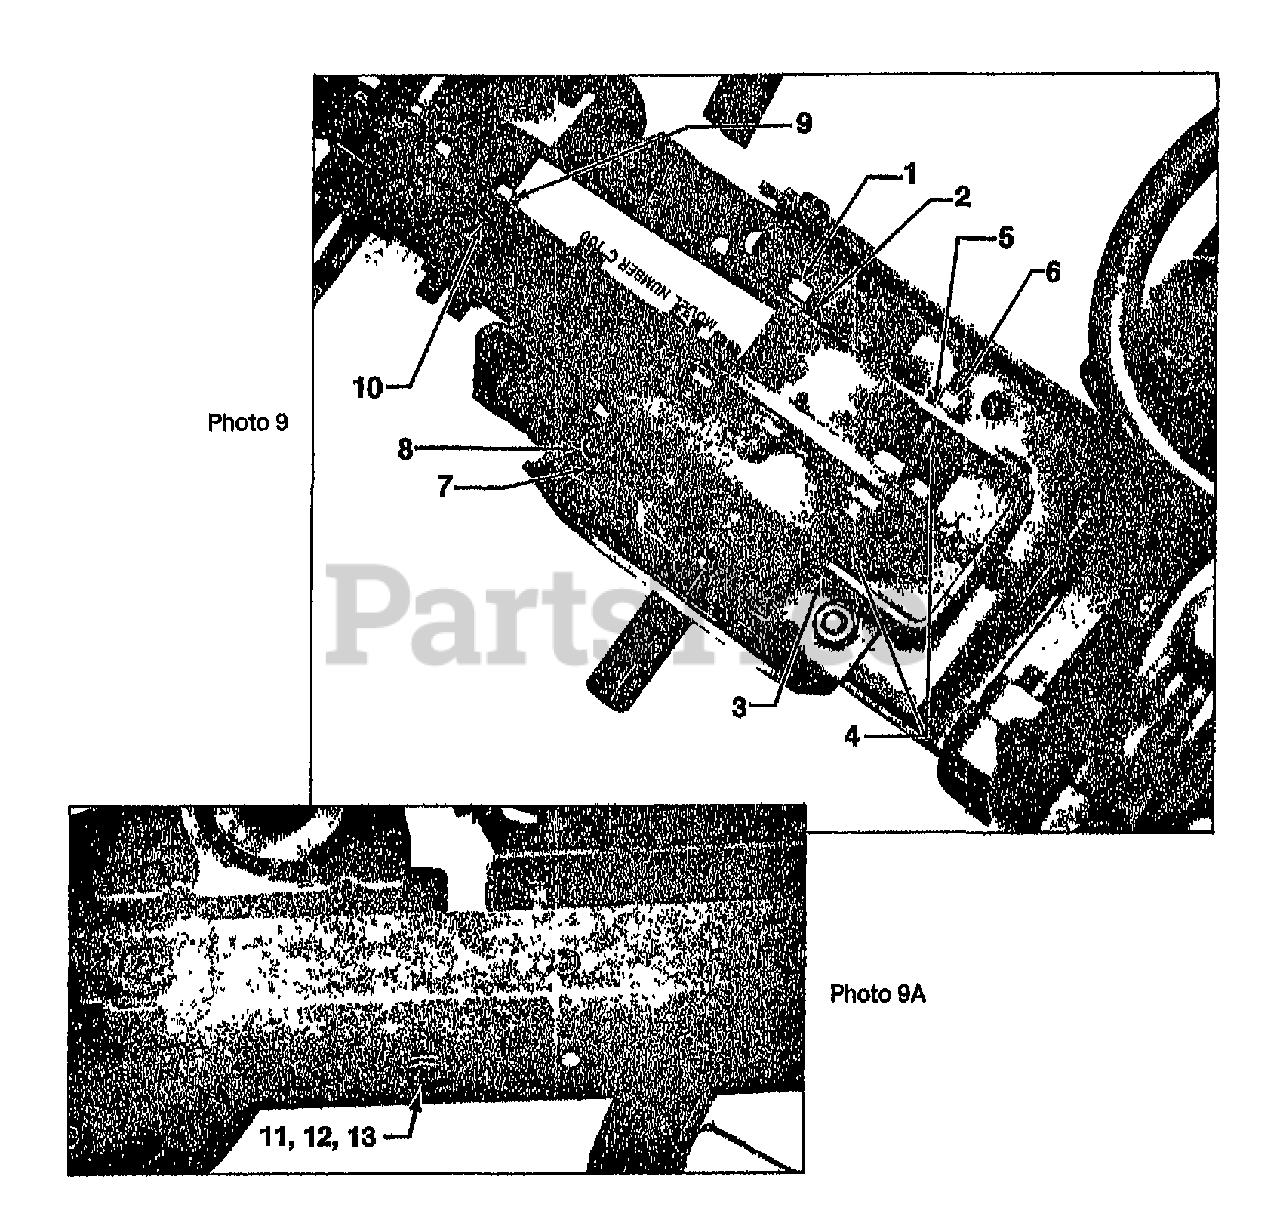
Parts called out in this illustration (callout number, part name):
1	SCR-HH 3/8-16X.75 G5 ZP
2	WASHER-LK .375 @ DEPL
3	SCR-HH 1/4-20X3.0 G5 ZP
4	SPACER-.438X.281X.960
5	WASHER-LK .25 ZP
6	NUT-HEX 1/4-20 ZP
7	WASHER-LK .312 ZP
8	NUT-HEX 5/16-18 ZP
9	SCR-HH 1/4-20X.625 (AROUND PERIMETER OF CHAIN CASE)
10	NUT-HF/LK 1/4-20 ZP (AROUND PERIMETER OF CHAIN CASE)
11	SCR-HH 3/8-16X1.0 G5 ZP
12	WASHER-LK .375 @ DEPL
13	WASHER-FLAT 3/8 SAE
